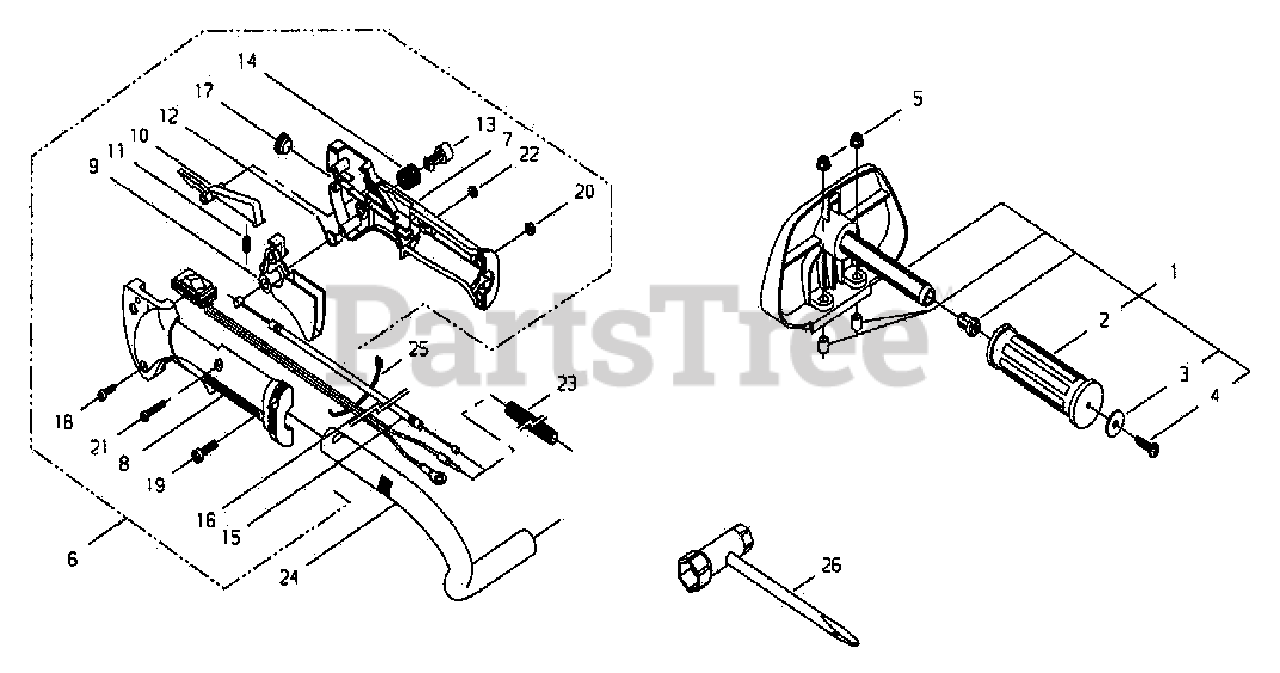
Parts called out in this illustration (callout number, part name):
1	HANDLE ASSY, FRONT
2	HANDLE, FRONT
3	WASHER 5 MM
4	SCREW 5×20
5	NUT M5
6	REAR HANDLE ASSY
7	CONTROL HANDLE - RIGHT
8	CONTROL HANDLE - LEFT
9	TRIGGER, THROTTLE
10	LOCKOUT, THROTTLE
11	SPRING, COMPRESSION
12	SPRING, TORSION
13	BUTTON, THROTTLE LOCK
14	SPRING, COMPRESSION
15	CABLE, THROTTLE
16	SWITCH ASSY, ON-OFF
17	PLUG, RUBBER
18	SCREW, TAPPING 4×16
19	SCREW M5×20
20	NUT M5
21	SCREW M4×23
22	NUT M4
23	TUBE, FLEXIBLE
24	HANDLE, REAR
25	STRAP, TIE
26	T-WRENCH 16×13
